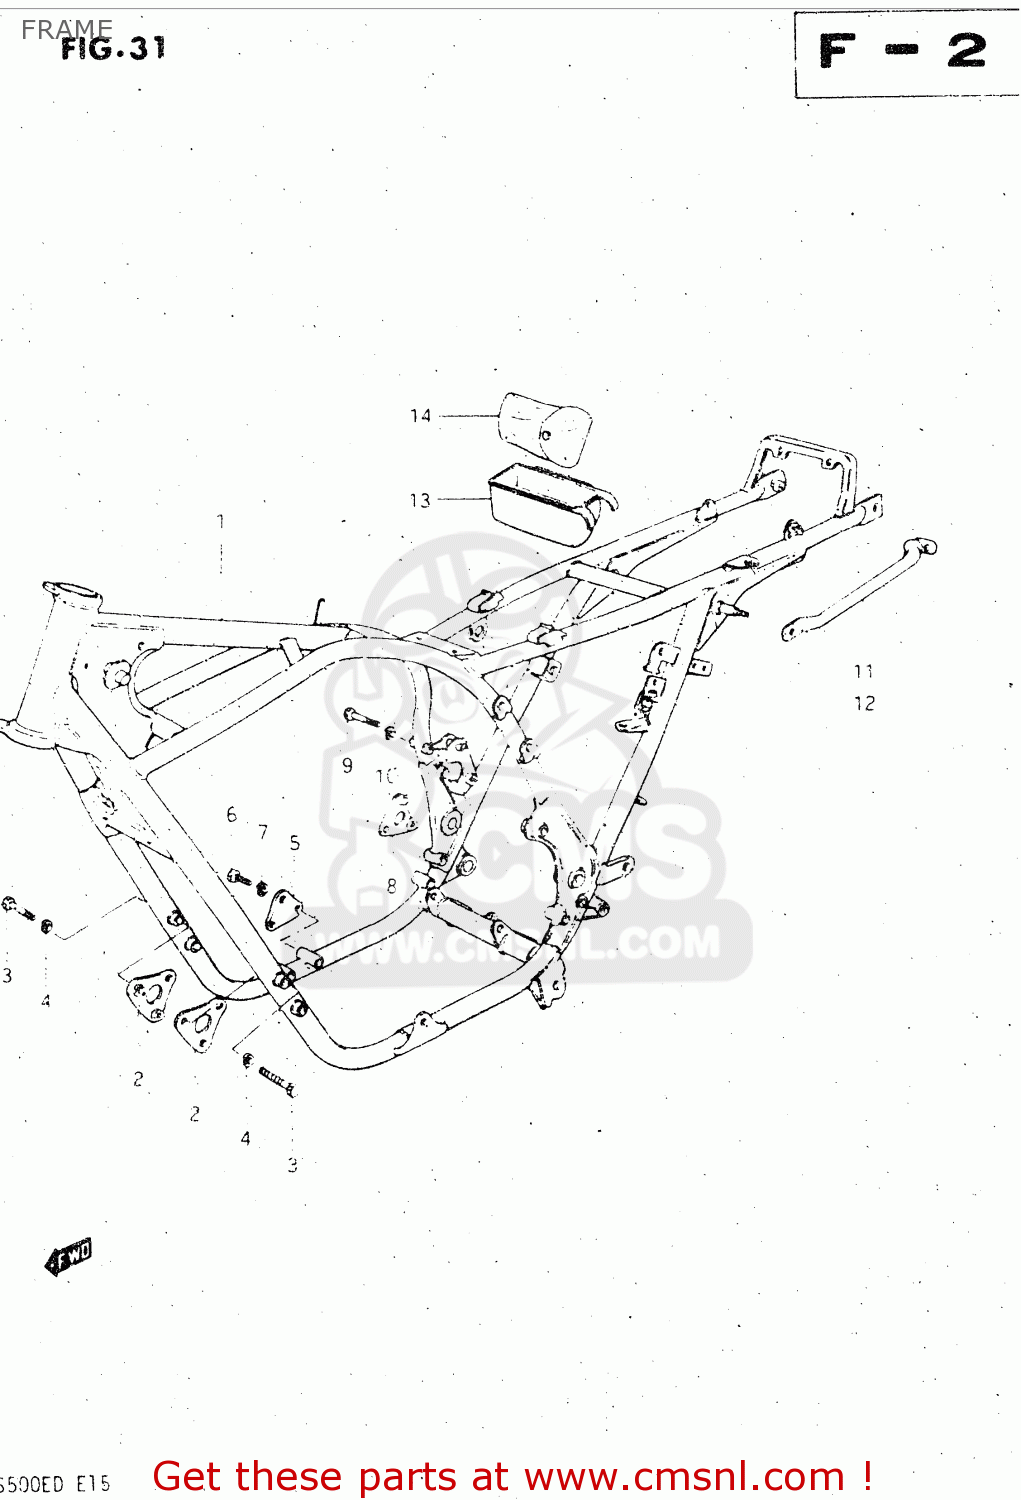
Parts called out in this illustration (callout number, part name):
1	FRAME
2	PLATE,ENGINE MOUNTING
3	BOLT
4	LOCK WASHER
5	PLATE,ENGINE MOUNTING
6	BOLT
7	LOCK WASHER
8	PLATE,ENGINE MOUNTING
9	BOLT 8X55
10	LOCK WASHER
11	GRIP,FRAME
12	GRIP, FRAME HANDLE LH
13	HOLDER,TOOL
14	TOOL SET
